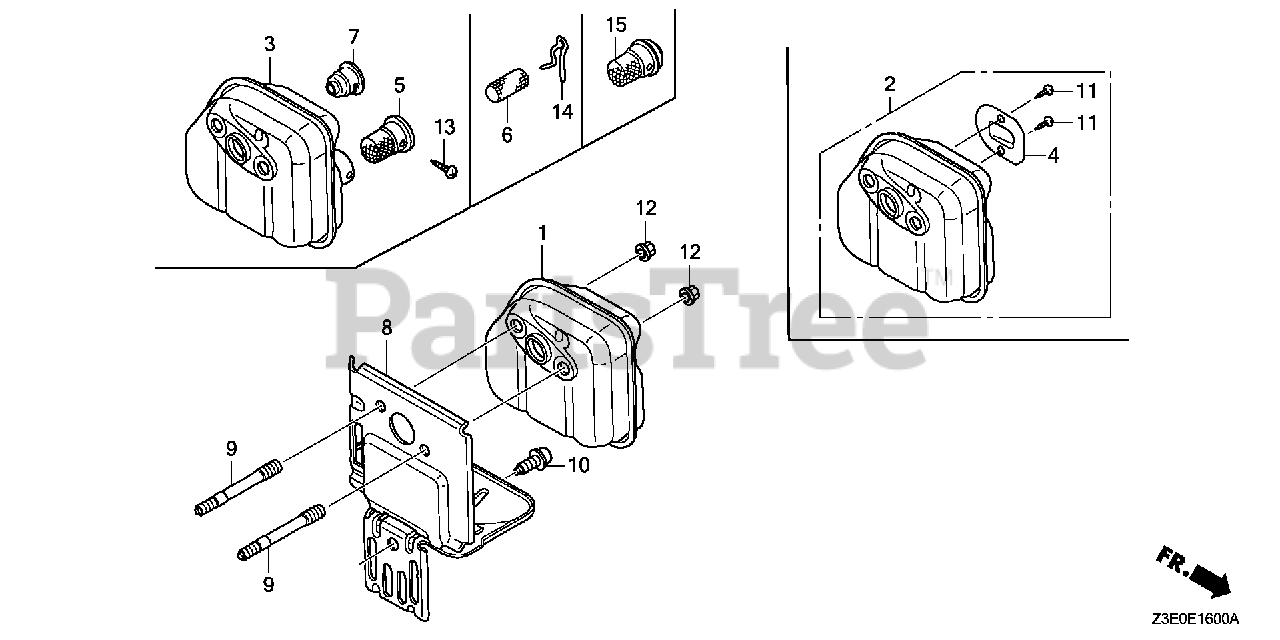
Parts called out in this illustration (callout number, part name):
2	MUFFLER
4	ARRESTER, SPARK
8	GUIDE, AIR EX.
9	BOLT, STUD (5X52)
10	BOLT, SOCKET (5X10) (CT)
11	SCREW, TAPPING (4X6) (TO INSTALL OPTIONAL SPARK ARRESTER)
12	NUT, SELF-LOCK (5MM)
